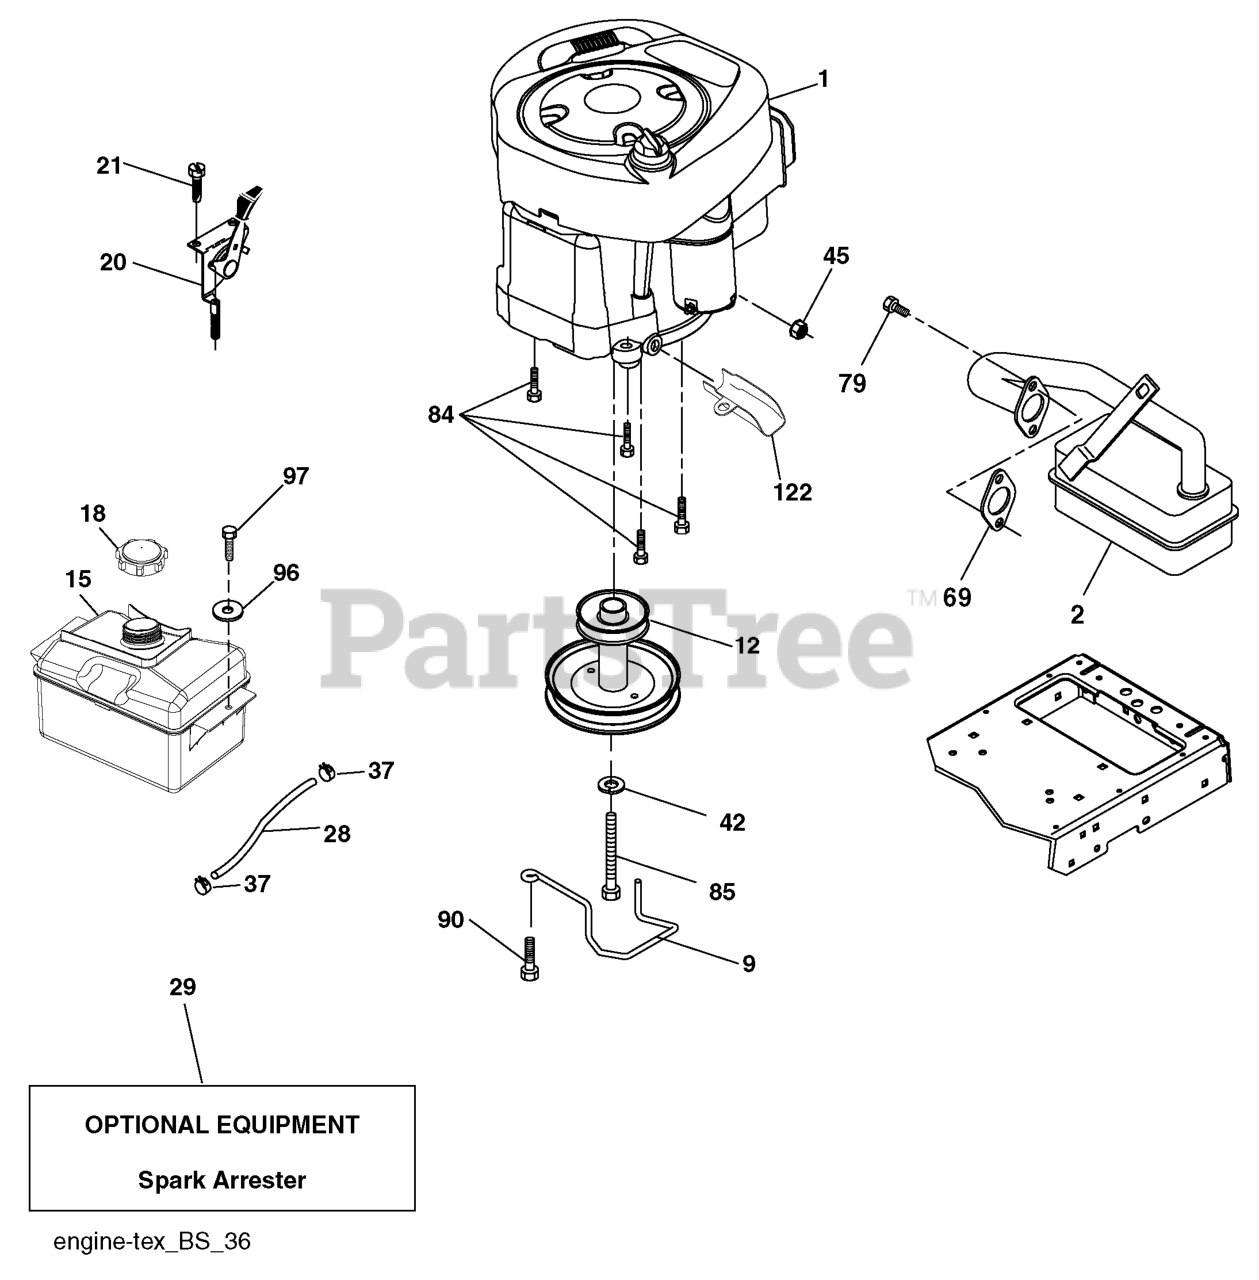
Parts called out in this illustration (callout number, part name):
2	MUFFLER.B&S.MODEL.21.11HP.OHV
9	KEEPER.BELT.ENGINE.3.25 (3 2)
12	PULLEY.ENG.CL.MECH.SLVR.LT/YT
15	RP TANK FUEL FRT 1.5 GAL
18	CAP.FUEL.2.25"VENTED"
20	CONTROL.TH/CK.C.
21	SCREW.#10 X 0.750.BOS
28	LINE.FUEL.20
29	KIT.SPARK ARRESTOR 794945 B&S
37	HOSE CLAMP
42	LOCKWASHER
45	NUT
69	REPL BY 532 27 22-93
79	SCREW.SOCKET HD.5/16-1
84	SCREW.3/8-16
85	BOLT
90	SCREW 3/8-16X1
96	WASHER
97	SCREW HEXWSHR 1/4-20X3/4
122	EXTENSION DRAIN OIL
